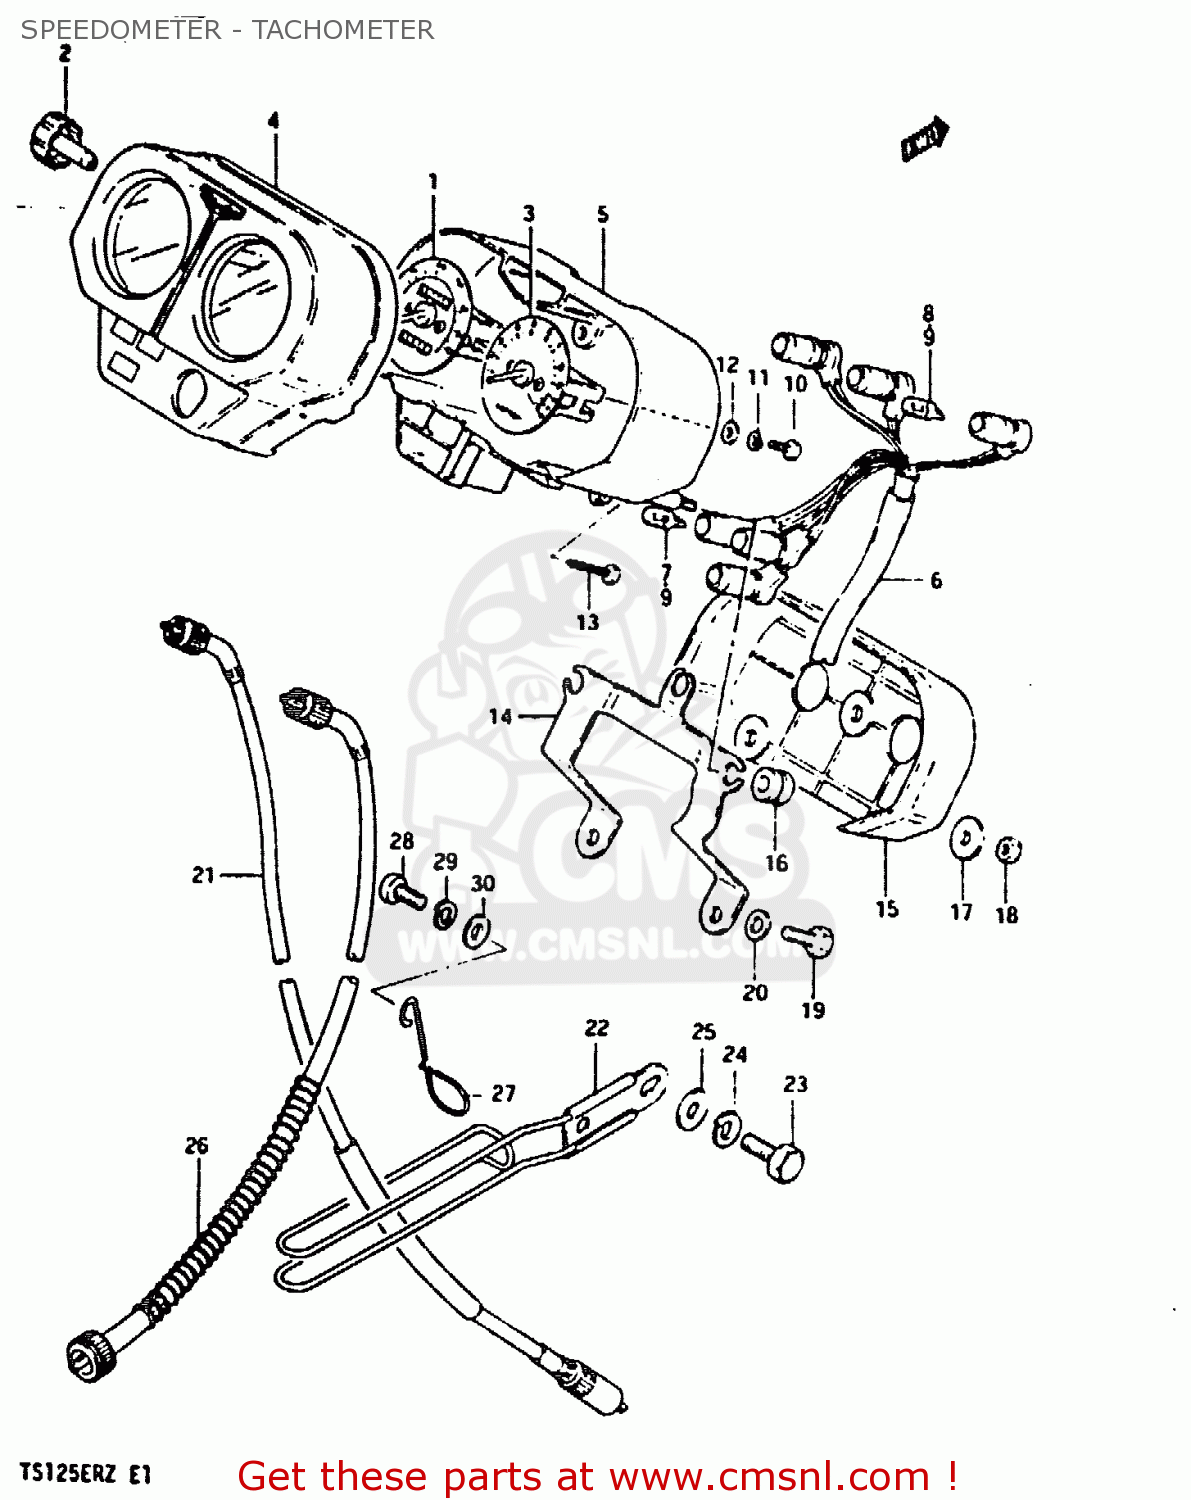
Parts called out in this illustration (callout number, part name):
1	SPEEDOMETER
2	KNOB,TRIP
3	TACHOMETER
4	HOOD,METER
5	CASE,INNER
6	SOCKET
9	BULB(12V3.4W,T10)
10	SCREW 4X10
11	LOCK WASHER
12	WASHER
13	SCREW
14	BRACKET,METER
15	COVER
16	CUSHION
17	WASHER
18	NUT
19	BOLT
20	WASHER
21	CABLE, SPEEDOMETER
22	GUIDE,CABLE
23	BOLT 8X12
24	LOCK WASHER
25	WASHER
26	CABLE ASSY,TACHOMETER
27	GUIDE, TACHOMETER CABLE
28	SCREW 6X12
29	LOCK WASHER
30	WASHER
